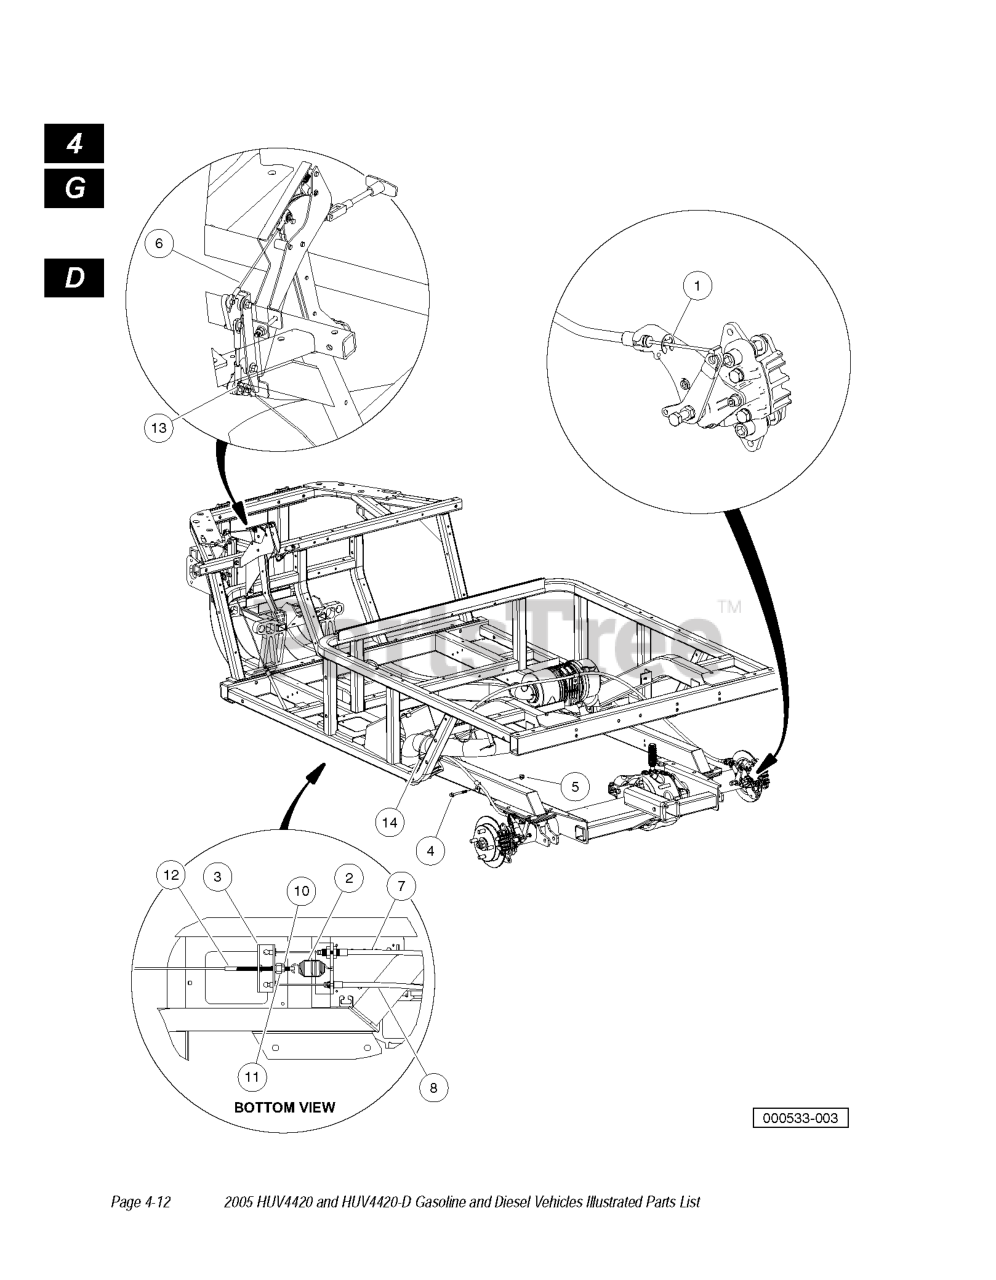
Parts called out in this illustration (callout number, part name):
1	E-CLIP, 1/2
2	SPRING, BRAKE RETURN
3	EQUALIZER BRACKET, PREC
4	BOLT FLG, M8X1.25X65
5	LOCK NUT, FLG M8 X 1.25 NYLON
6	CABLE, CRANK, BELL, FRONT
7	CABLE, NONCOATED, PBRAKE, LEFT
8	CABLE, NONCOATED, PBRAKE, RGHT
9	KIT, CABLE, BRAKE, CRANK, FR
10	NUT, 5/16-24 HEX
11	NUT, 5/16-24 HEX CONE
13	PIN,CUT COTTER
14	TIE WRAP , 11" NYLON
